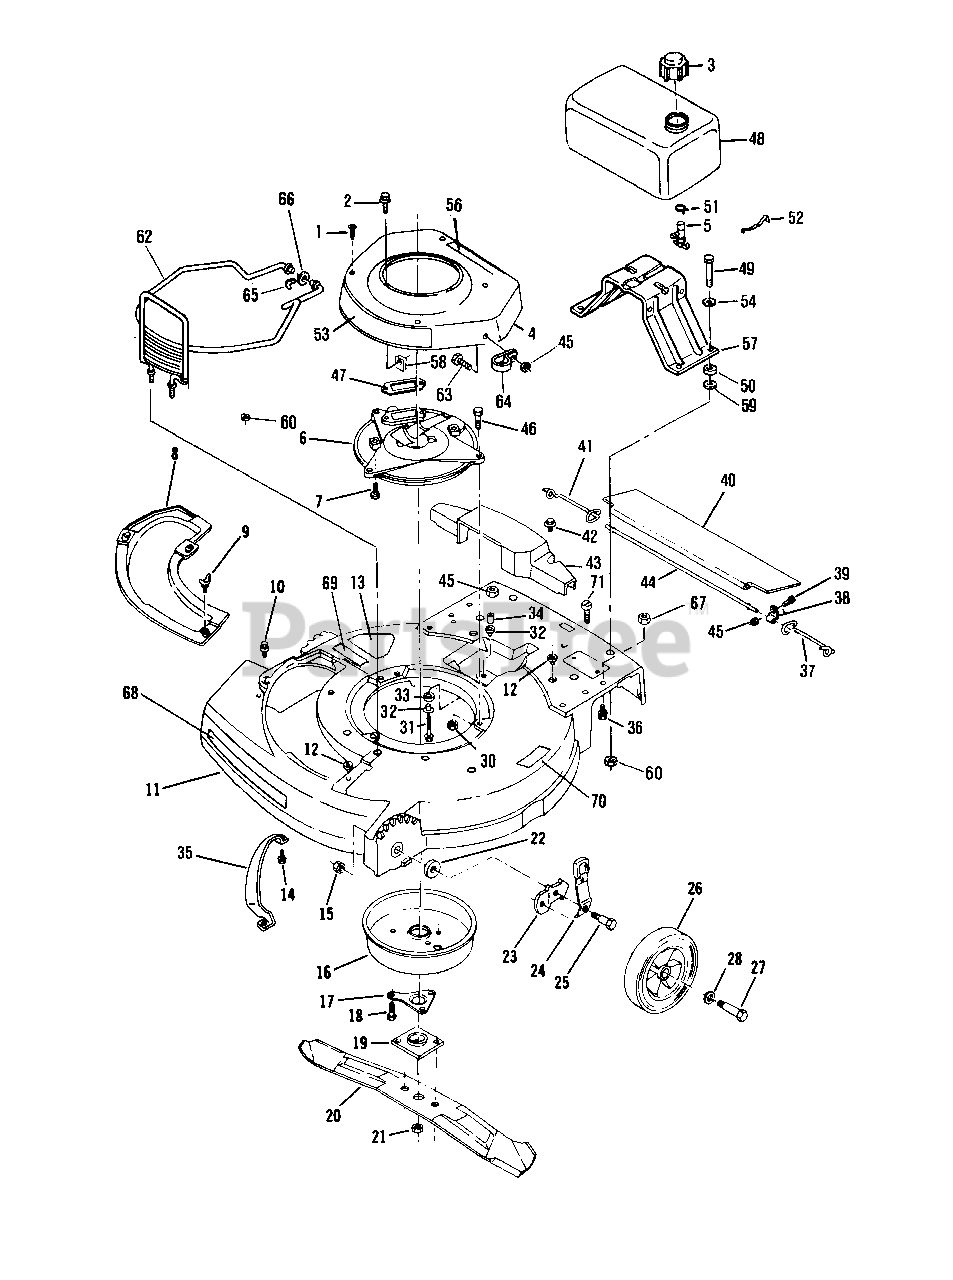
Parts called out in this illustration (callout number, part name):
1	Screw
2	Screw
3	Fuel Cap
4	Shroud-Engine
5	Fuel Shut-Off Assembly
6	Plate-Muffler
7	Screw-Muffler Plate to Block
8	Cover Plate
9	Wing Screw
10	Screw-Plate and Chute Mounting
11	Housing
12	Grommet
13	Decal-Blade Contact Warning
14	Screw
15	Nut
16	Muffler Cover Assembly
17	Support-Crankshaft
18	Screw-Muffler to Muffler Plate
19	Collar and Plate Assembly
20	Blade-21"
21	Nut-Blade
22	Washer
23	Bracket-Wheel Height Adjust
24	Knob and Spring Assembly
25	Bolt-Shoulder
26	Wheel-Front
27	Bolt-Wheel-Front
28	Washer
30	Nut-Muffler Plate to Housing and Engine Guard
31	Screw
32	Spacer
33	Grommet
34	Spacer
35	Toe Bar
36	Screw-Handle Bracket
37	Spring-L.H.
38	Clamp
39	Screw
40	Shield-Trailing
41	Spring-R.H.
42	Screw-Axle Cover Mounting
43	Cover-Drive Axle
44	Rod-Trailing Shield
45	Nut
46	Screw-Muffler Plate to Housing
47	Gasket-Exhaust
48	Fuel Tank
49	Bolt
50	Grommet
51	Clamp
52	Spring
53	Applique
54	Washer-Tank Mounting
56	Decal-Fuel Mixture
57	Bracket-Tank Mounting
58	Retainer
59	Washer
60	Nut
62	Guard-Engine
63	Screw
64	Clamp
65	Hair Pin
66	Washer-Spring
67	Nut-Handle Bracket
68	Decal
69	Decal
70	Decal
71	Screw
